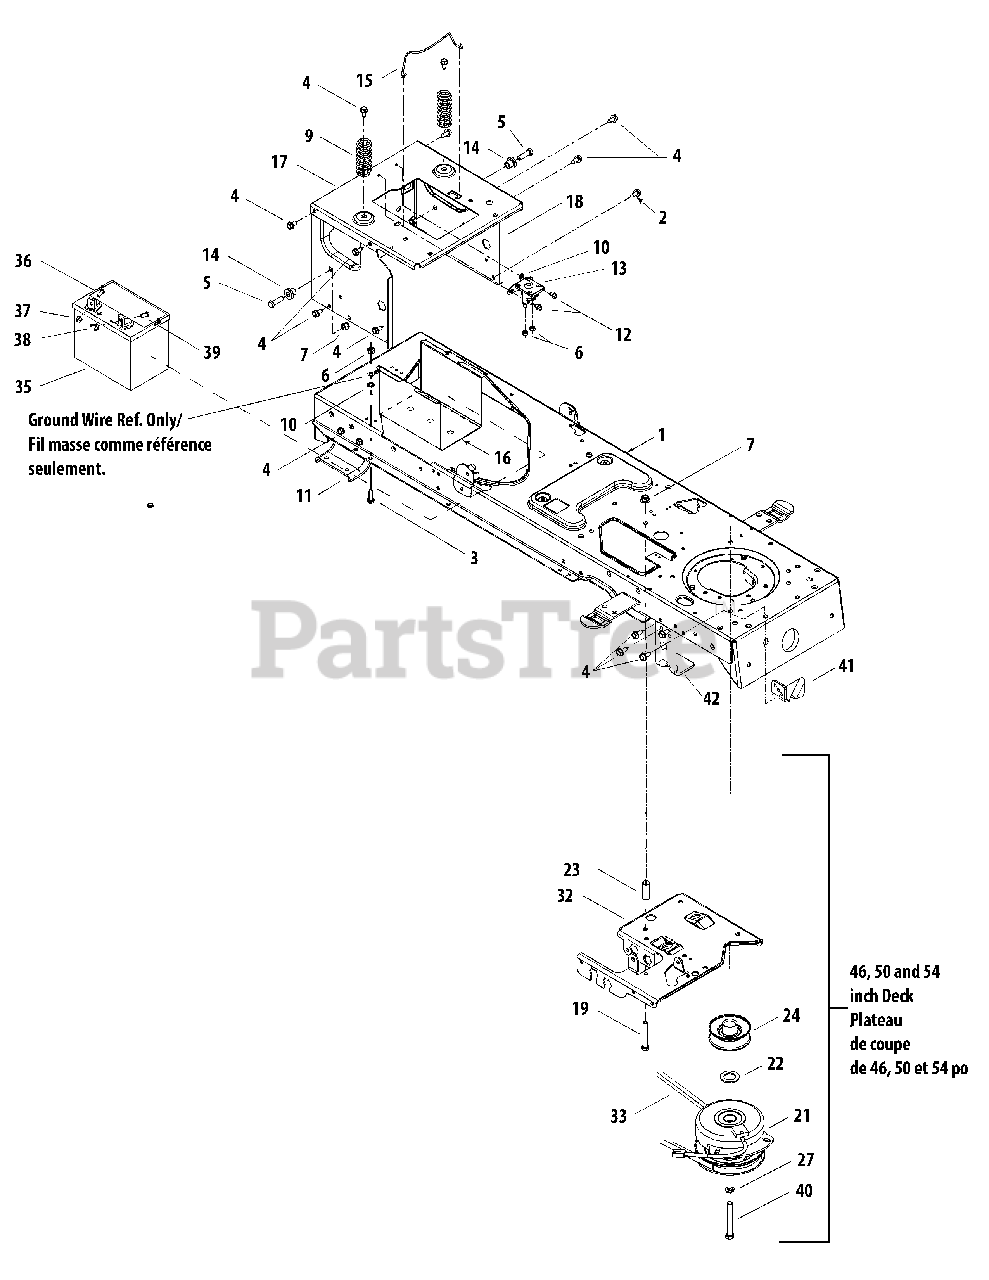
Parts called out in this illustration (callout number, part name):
1	Lower Frame Assembly
2	Hex Wash HD S-Tapp Scr 5/16-18 x
3	Thd Form ing Scr. 1/4-20 x .75 Lg.
4	S-Tapp Scr 5/16-18 x .75
5	Hex Bolt 3/8-16 x 1.25
6	Hex L-Flanged Nut 1/4-20 Gr. F Ny lon
7	Flange Lock-Nut 3/8-16 Gr. F Ny lon
9	Compression Spring 1.28 x 3.125
10	Ext. L-Washer 1/4 ID
11	Axle Bracket
12	Hex Wash S-Tapp Scr 1/4-20 x .50
13	Solenoid
14	Shoulder Spacer .38 x 1.0 x .70
15	Battery Re tainer Rod
17	Frame Seat Bracket
18	Upper Frame (800)
19	Hex Cap Screw, 3/8-16 x 2.25 Gr. 5
21	Electric PTO Clutch 46 & 50" Deck
21	Electric PTO Clutch 54" Deck
22	Flat Washer 1.03 ID x 1.64 OD x .095
23	Spacer .385 ID x .635 OD x 1.54
24	Engine Pulley (w/Hydrostatic models)
24	Engine Pulley, 3.56 OD
27	Lockwasher 7/16 ID
32	Steering Support Bracket
33	V-Belt Type A Sec x 118.20 (46" Deck)
33	V-Belt Type A Sec x 138.0 (54" Deck)
35	Battery 245 CCA (Dry)
36	Hex Flg. Bolt 1/4-10 x .75 Gr. 5
37	Sems Hex Nut 1/4-20
38	Wing Nut 1/4-20 Thd.
39	Shoulder Screw, 1/4-20
40	Hex Hd. Cap Scr. 7/16-20 x 3.5
41	Bracket Clutch (w/ 54" Deck)
42	Bracket - Deck Stop (w/54" Deck)
